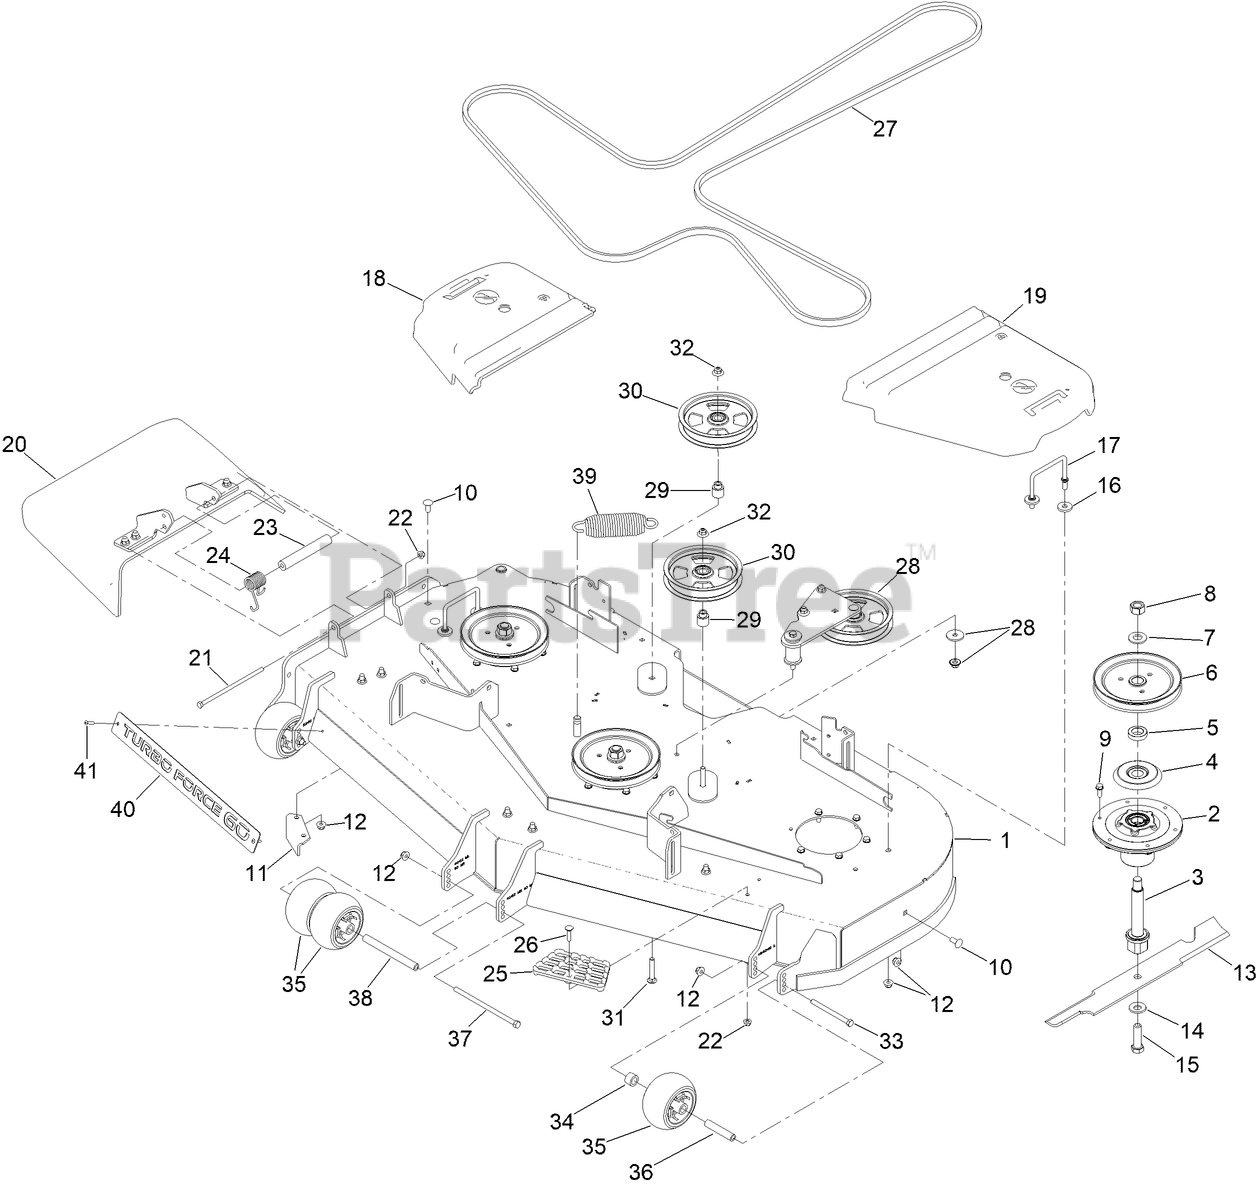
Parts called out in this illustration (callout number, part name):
1	DECK DECAL ASM
2	SPINDLE ASM
3	SHAFT-SPINDLE
4	SHIELD-BEARING
5	SPACER-PULLEY
6	SHEAVE-DRIVE, BLADE
7	WASHER
8	NUT-HEX
9	SCREW-TAPTITE
10	SCREW-CARR
11	BAFFLE-DISCHARGE
12	NUT-HF, NI
13	BLADE-ROTARY, 20.5IN (HI FLOW)
14	WASHER-BELLEVILLE
15	SCREW-BLADE
16	WASHER
17	WIREFORM-COVER
18	COVER-BELT, RH
19	COVER-BELT, LH
20	RUBBER DEFLECTOR ASM
21	SCREW-HH
22	NUT-HF, NI
23	SPACER
24	SPRING-TORSION
25	STEP-DECK
26	SCREW-CARR
27	BELT-V
28	IDLER ARM ASM
29	BUSHING, IDLER
30	PULLEY-IDLER, FLAT
31	SCREW-CARR
32	NUT-FLANGE, NI
33	SCREW-HH
34	TUBE-SPACER
35	ROLLER-SCALP, ANTI
36	TUBE-SHAFTING
37	SCREW-HH
38	SPACER-WHEEL
39	SPRING-EXTENSION
40	PLATE-TURBO FORCE [BLACK]
41	RIVET-TRIFOLD
